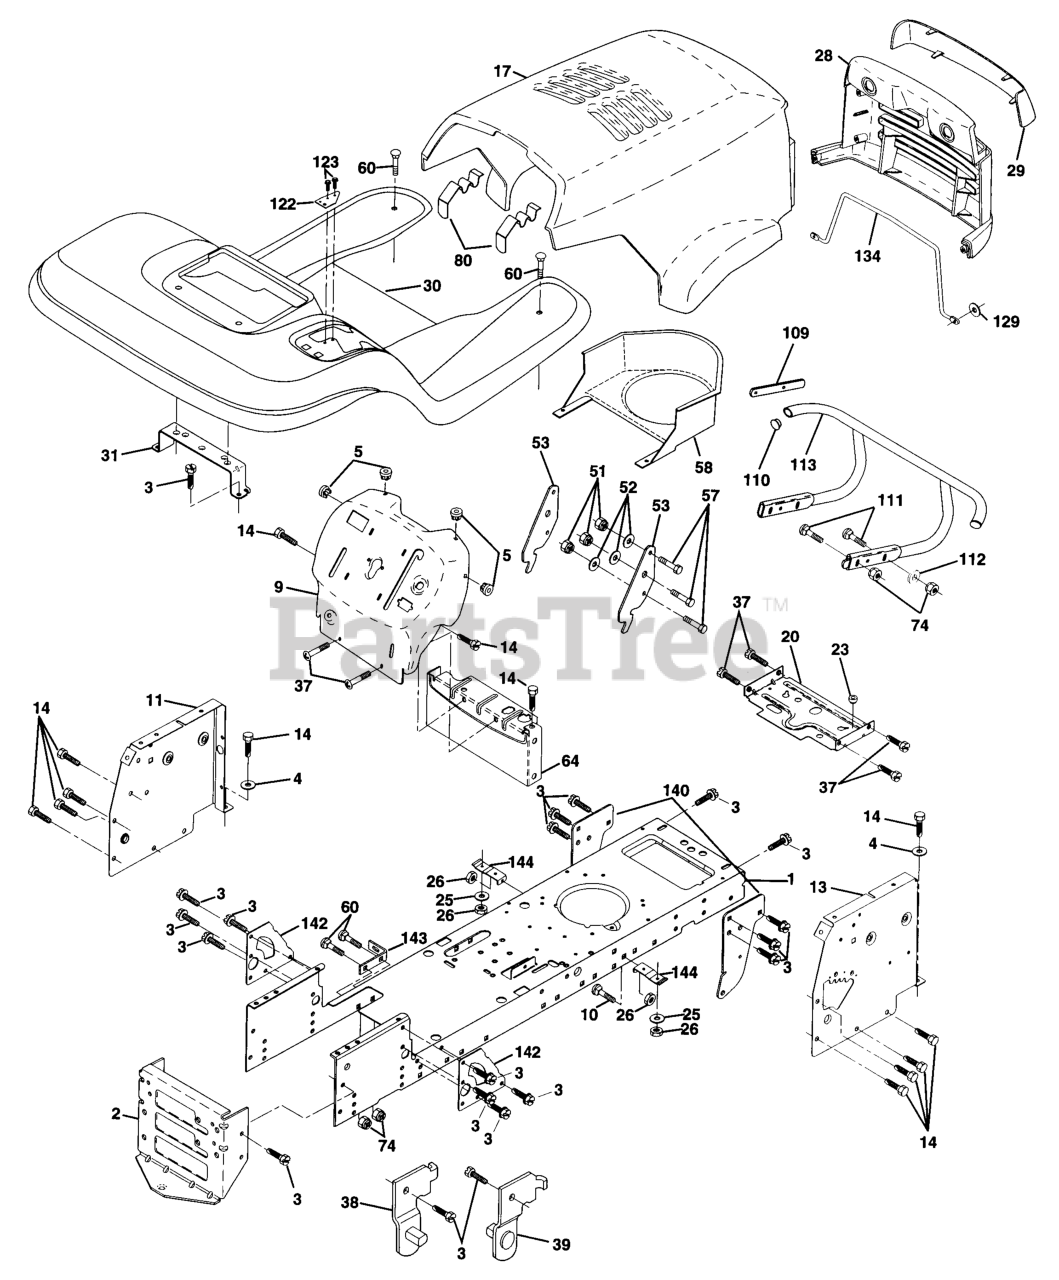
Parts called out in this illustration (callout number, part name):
1	CHASSIS WELDMENT
2	STRETCH DRAWBAR
3	SCREW
4	Washer 13/32 x 3/4 x 16 Ga.
5	BUMPER.RUBBER.HOOD
9	DASH PANEL
10	BOLT D
11	PANEL DASH LH
14	SCREW LT
17	HOOD - LT/YT
20	PLATE MTG
23	BUSHING.SNAP.NYL.BLK.
25	WASHER
26	NUT
28	GRILLE LT/PL HUSQVARNA
29	LENS LT/PL HUSQVARNA
30	FENDER FOOTREST
31	BRACKET.SUPPORT.FENDER
37	Screw Thdrol 6/16-18 x 1/2 TYT
38	BRACKET LH PIVOT
39	BRACKET RH PIVOT
51	LOCKNUT.NYLOC.1/4-20
52	WASHER
53	BRACKET PNT PICK OFF LT/PL
57	BOLT
58	AIR DUCT P/L/LT
60	Bolt Rdhd Sqnk 3/8-16unc x 3/4
64	DASH LOWER
80	LATCH HOOD
109	BRACKET BUMPER
110	PLUG PLASTIC
111	Bolt Rdhd 3/8-16unc x 1-1/2
112	WASHER
113	BUMPER ASM
129	WASHER
134	ROD SUPPORT HOOD LT/PL HUSQ
140	BRACKET CHASSIS FRONT
142	PLATE REINFORCEMENT
143	BRACKET, SWAY BAR
144	BRACKET FOOTREST
146	SCREW TORX HD 5/16X18
